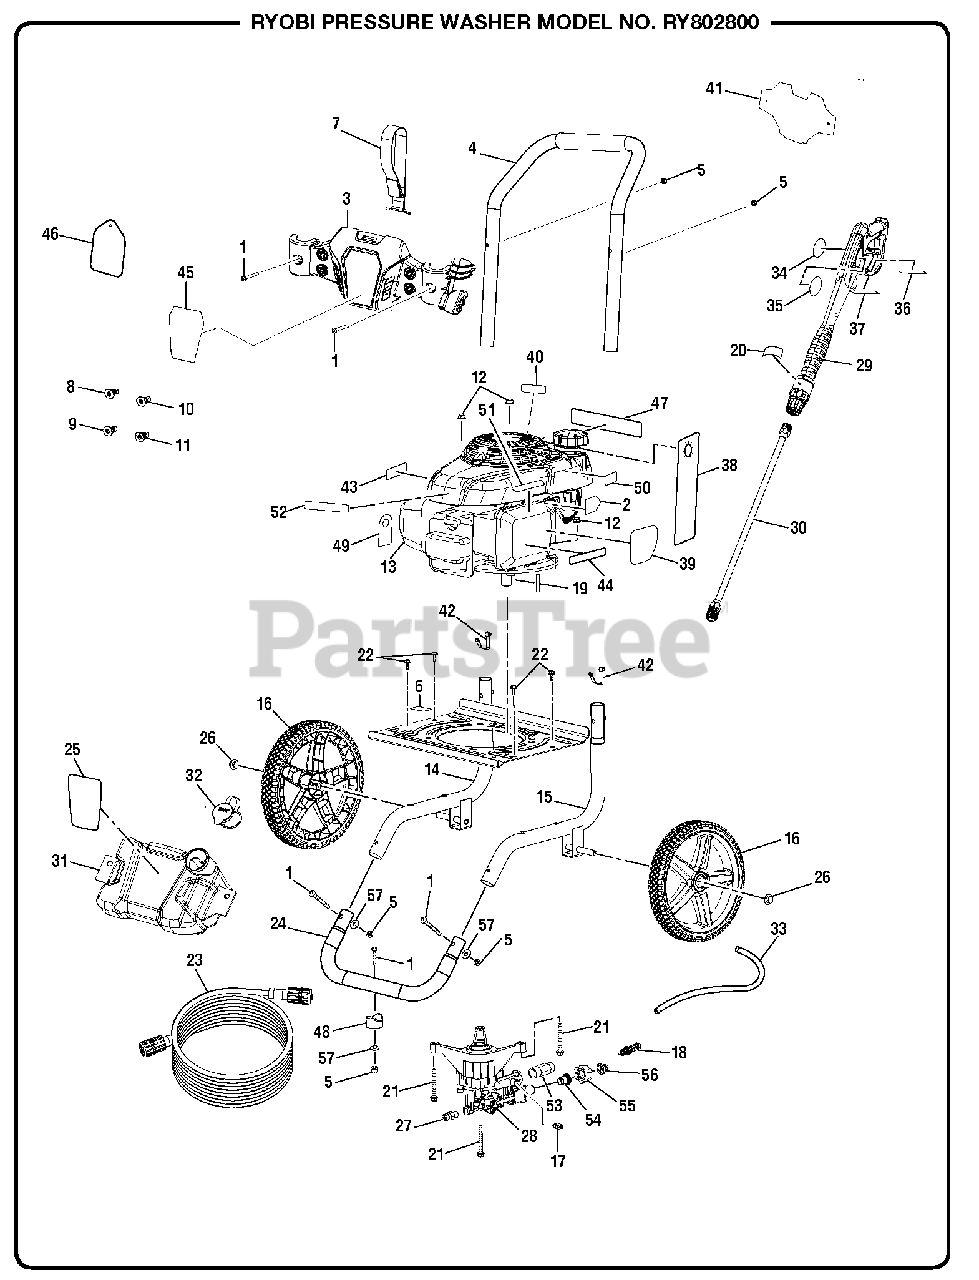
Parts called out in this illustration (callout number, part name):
1	Screw (M6 x 48 mm, T30 Torx Pan Hd.)
2	Engine On/Off Label
3	Hose and Nozzle Holder
4	Handle w/Foam
5	Lock Nut (M6 x 1)
6	Oil Fill Location Label
7	Hose Holder Strap
8	40deg Nozzle
9	Soap Nozzle
10	25deg Nozzle
11	0deg Nozzle
12	Flange Lock Nut (M8 x 1.25)
13	Engine (Honda GCV 160, 160cc OHC Vertical)
14	Main Frame Assembly
15	Main Frame Assembly
16	Wheel
17	Detergent Suction Kit
18	Pump Unloader Valve
19	Output Shaft Key
20	Trigger Handle Power Control Label
21	Flange Bolt (M8 x 60 mm, Hex Hd.)
22	Flange Bolt (M6 x 16 mm, Hex Hd.)
23	Hose (25 ft.)
24	Front Frame
25	Detergent Tank Label
26	Push Cap Nut
27	Thermal Release Valve
28	Pump
29	Trigger Handle Assembly
30	Extension Wand
31	Soap Tank
32	Soap Tank Cap
33	Chemical Siphon Tube
34	Trigger Handle Logo Label
35	Trigger Handle Warning Label (Eng)
36	Trigger Handle Warning Label (Fr/Sp)
37	Trigger Handle Rating Label
38	Danger Hangtag
39	Engine Control Label
40	Combustion Label
41	Quick Start Label
42	Lock Button w/Spring Clip
43	Hot Surface
44	EMC Label
45	Performance Label
46	Nozzle Hangtag
47	Danger Label
49	Dipstick Hangtag
50	No E85 Label
51	Inquiries Label
52	Honda Brand Label
53	Outlet Tube
56	Filter Screen (Pump Inlet)
57	Washer (1/4 in.)
